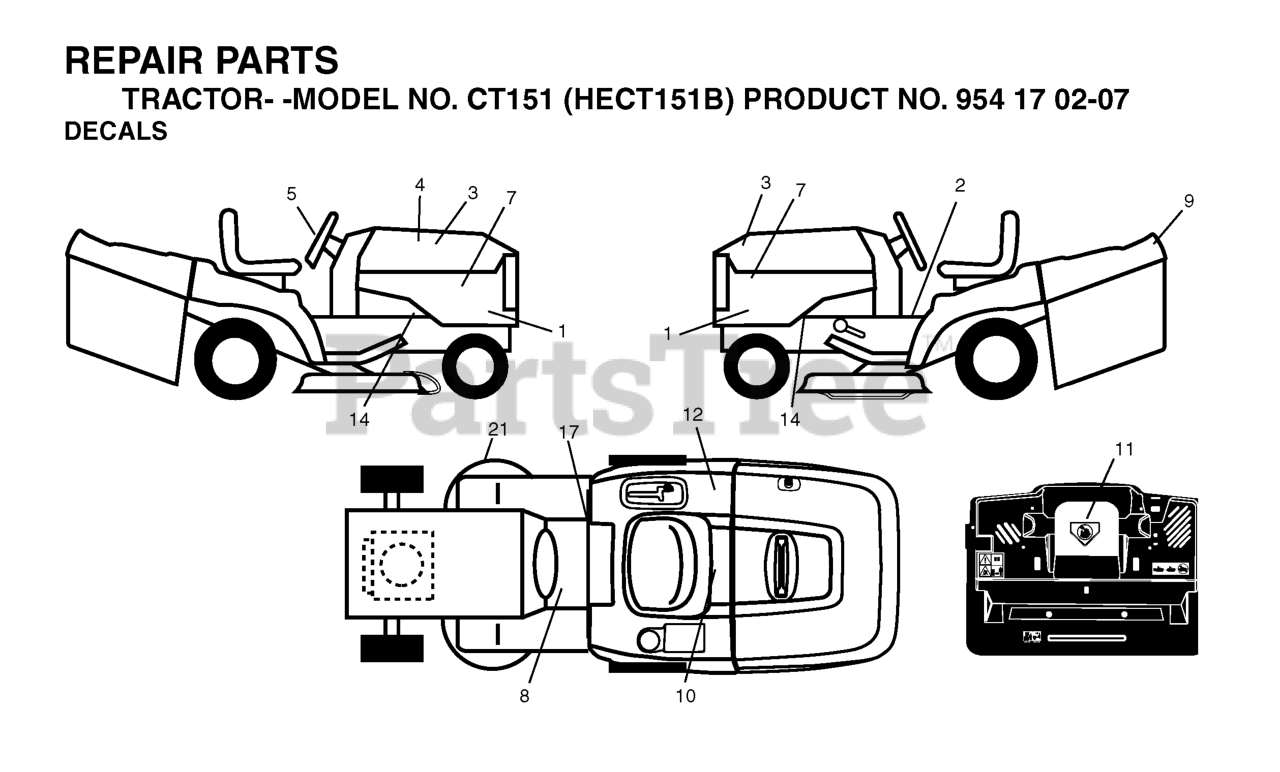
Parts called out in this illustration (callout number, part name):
2	DECAL READ OWNER'S MAN SYMS
5	DECAL.STEERING.HUSQ.BLUE
7	DECAL.HOOD.HUSQVARNA.INTERNATI
8	DECAL
10	DECAL BTRY SYMBOLS
11	DECAL.INTERNATIONL.CUTFINGER
12	Decal, Fender 100 DB/CE
17	DECAL PARK BRAKE
